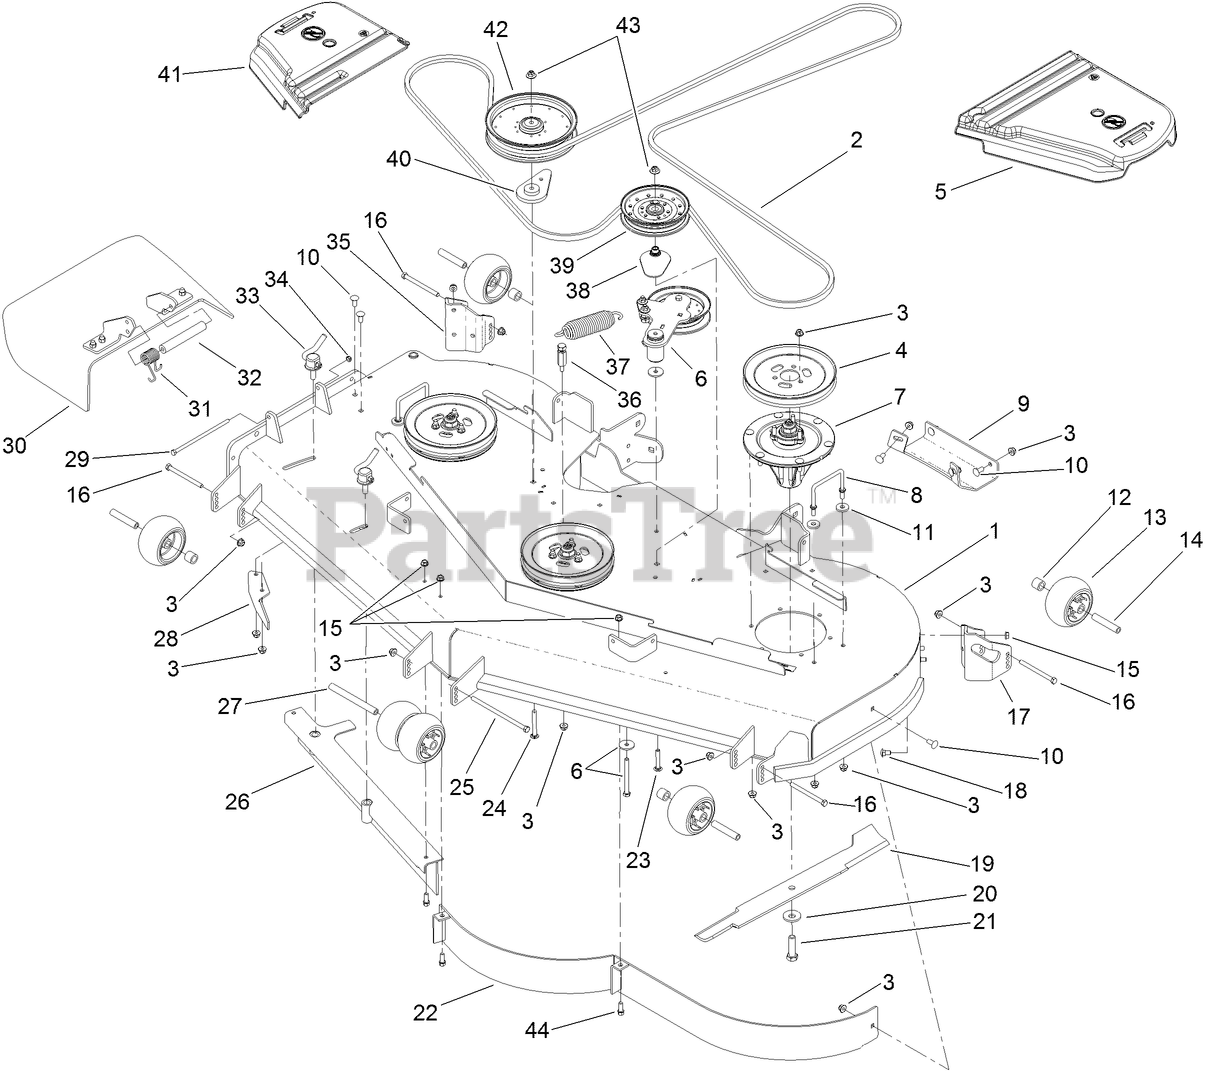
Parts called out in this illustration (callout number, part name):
1	DECK DECAL ASM
2	BELT-V
3	NUT-HF, NI
4	Pulley
5	COVER-BELT, LH
6	IDLER ARM ASM
7	SPINDLE ASM
8	WIREFORM-COVER
9	PLATE-SKID
10	SCREW-CARR
11	WASHER
12	TUBE-SPACER
13	ROLLER-SCALP, ANTI
14	TUBE-SPANNER
15	NUT-HHF, WHIZ
16	SCREW-HH
17	MOUNT-WHEEL, LH
18	SCREW-CARR
19	BLADE-HI FLOW, 24.5 INCH
20	Washer-Blade Bolt, Heavy
21	SCREW-BLADE
23	BOLT-CARR, SHORT NECK
24	SCREW-CARR
25	SCREW-HH
27	SPACER-WHEEL
28	BAFFLE-DISCHARGE
29	SCREW-HH
30	RUBBER DEFLECTOR ASM
31	SPRING-TORSION
32	SPACER
33	LEVER ASM
34	NUT-LOCK, NI
35	MOUNT-WHEEL, RH
36	ANCHOR-SPRING, TALL
37	SPRING-EXTENSION
38	SPACER-PULLEY
39	PULLEY-IDLER, FLAT
40	SPACER-IDLER
41	COVER-BELT, RH
42	PULLEY-IDLER
43	NUT-FLANGE, NI
44	SCREW-HWH
